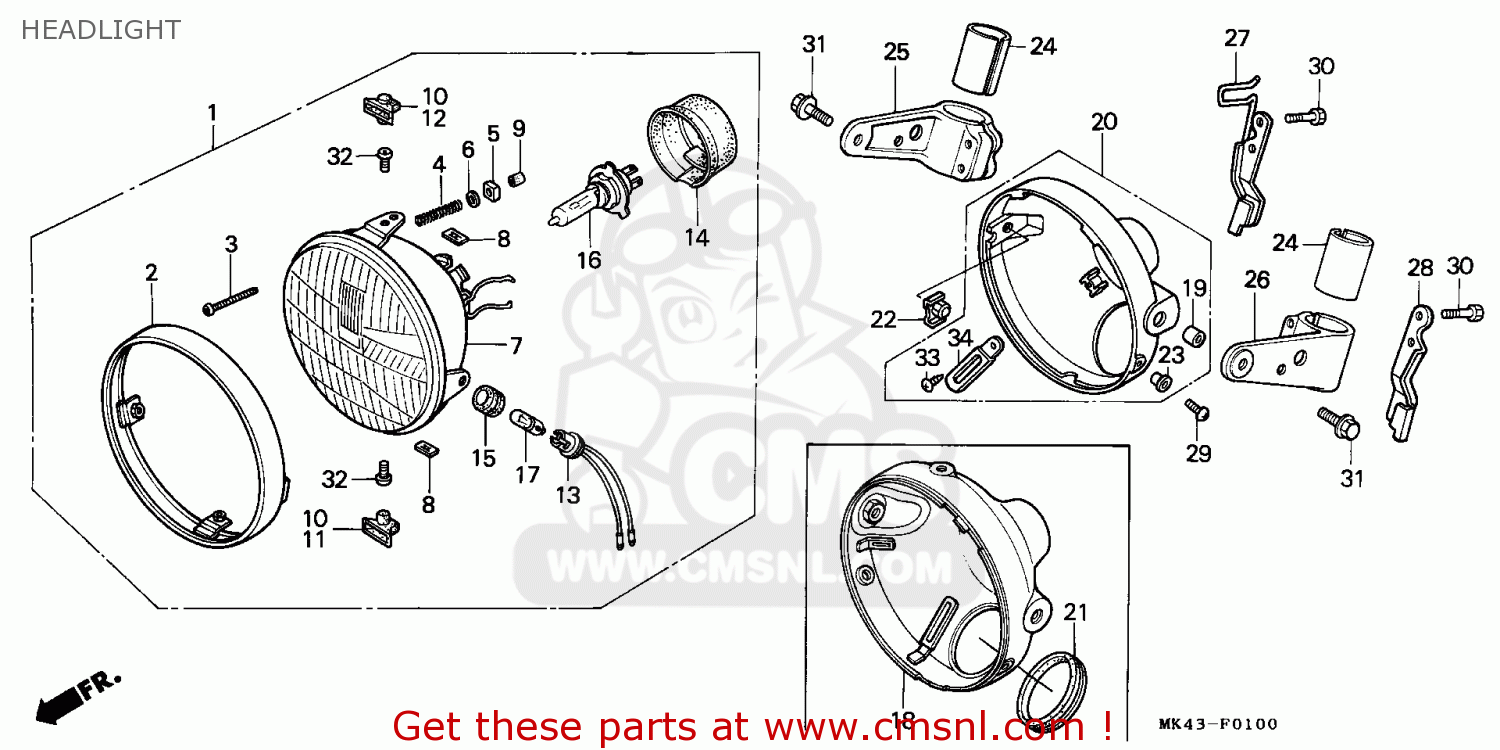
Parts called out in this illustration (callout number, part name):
1	HEADLIGHT ASSY.(1
2	RIM,HEADLIGHT
3	SCREW.BEAM ADJUST
4	SPRING BEAM
5	NUT, BEAM ADJUST
6	WASHER,BEAM A.D,
7	HEADLIGHT UNIT
8	NUT,UNIT HOLDER
9	COVER,SCREW
10	COVER,BEAM ADJUST
13	SOCKET.,POSITION
14	COVER,RUBBER
15	RUBBER,JOINT
16	BULB,HEADLIGHT
17	BULB,POSITION 12V 4W
19	COLLAR,H/L.CASE.
20	CASE ASSY.,HEADLI
22	NUT,HEADLIGHT CAS
24	RUBBER HD LT STAY
25	STAY,R.HEADLIGHT
26	STAY,L.HEADLIGHT
27	STOPPER,R.WINKER
28	STOPPER,L.WINKER
29	SCREW,SPEC.5X12
30	BOLT,SPECIAL FLAN
31	BOLT,FLANGE,8X20
32	SCREW PAN 5X8
33	SCREW,TAP 4X10
34	CLIP,WIRE
